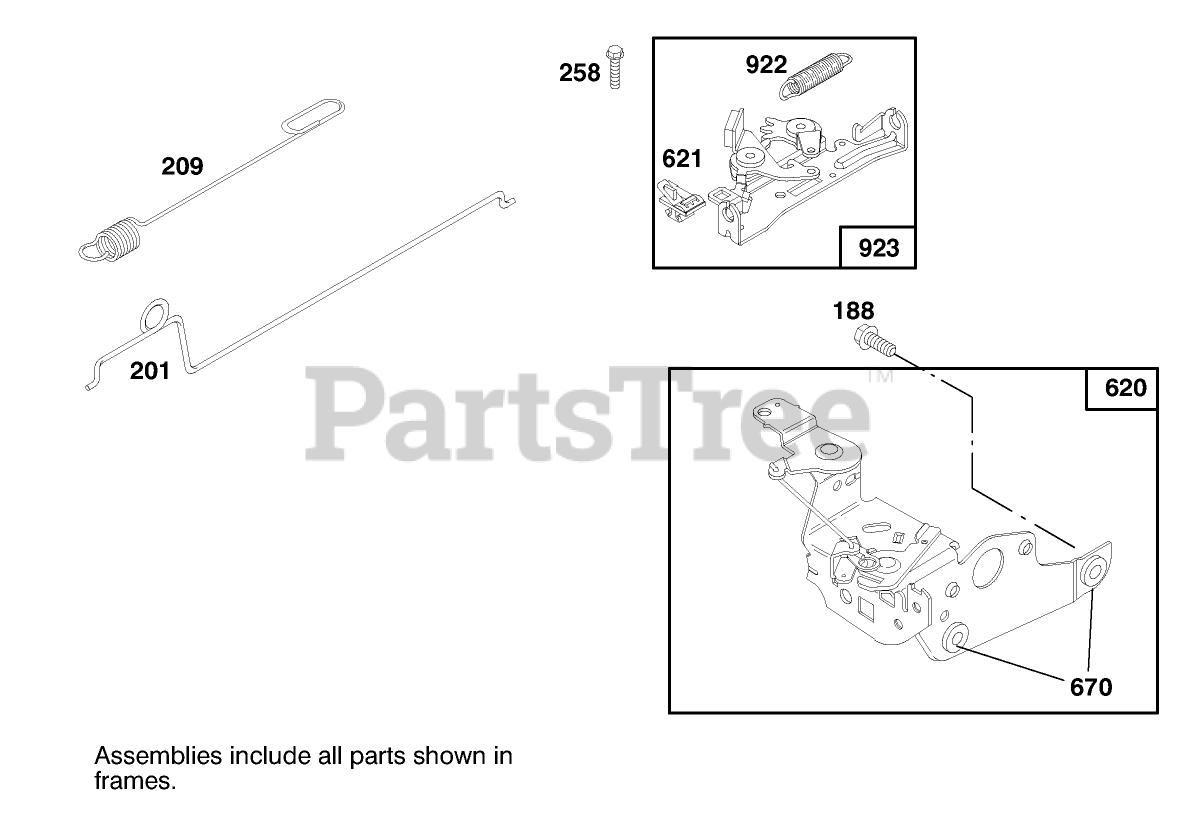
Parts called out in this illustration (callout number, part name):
188	Screw-Hex.
201	Link-Govemor
209	Governor Spring
258	Screw-Sem
620	Bracket-Control
621	Switch
670	Spacer
922	Brake Spring
923	Brake
